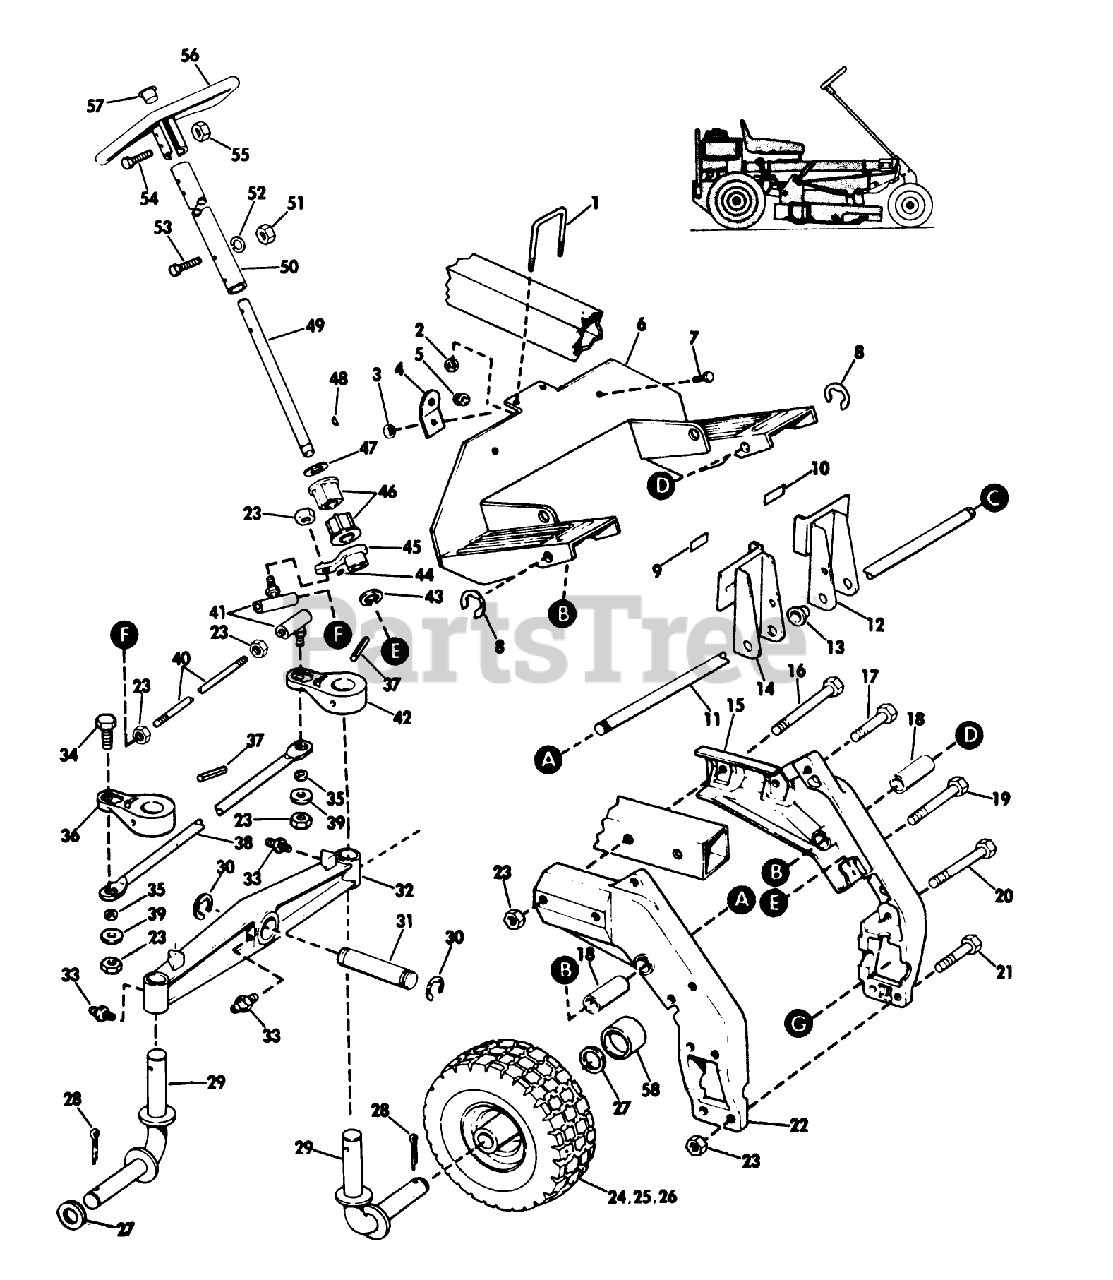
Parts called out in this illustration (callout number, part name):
5	Bushing
33	Grease Fitting
34	Screw-King Pin
55	Nut-Steering Shaft
